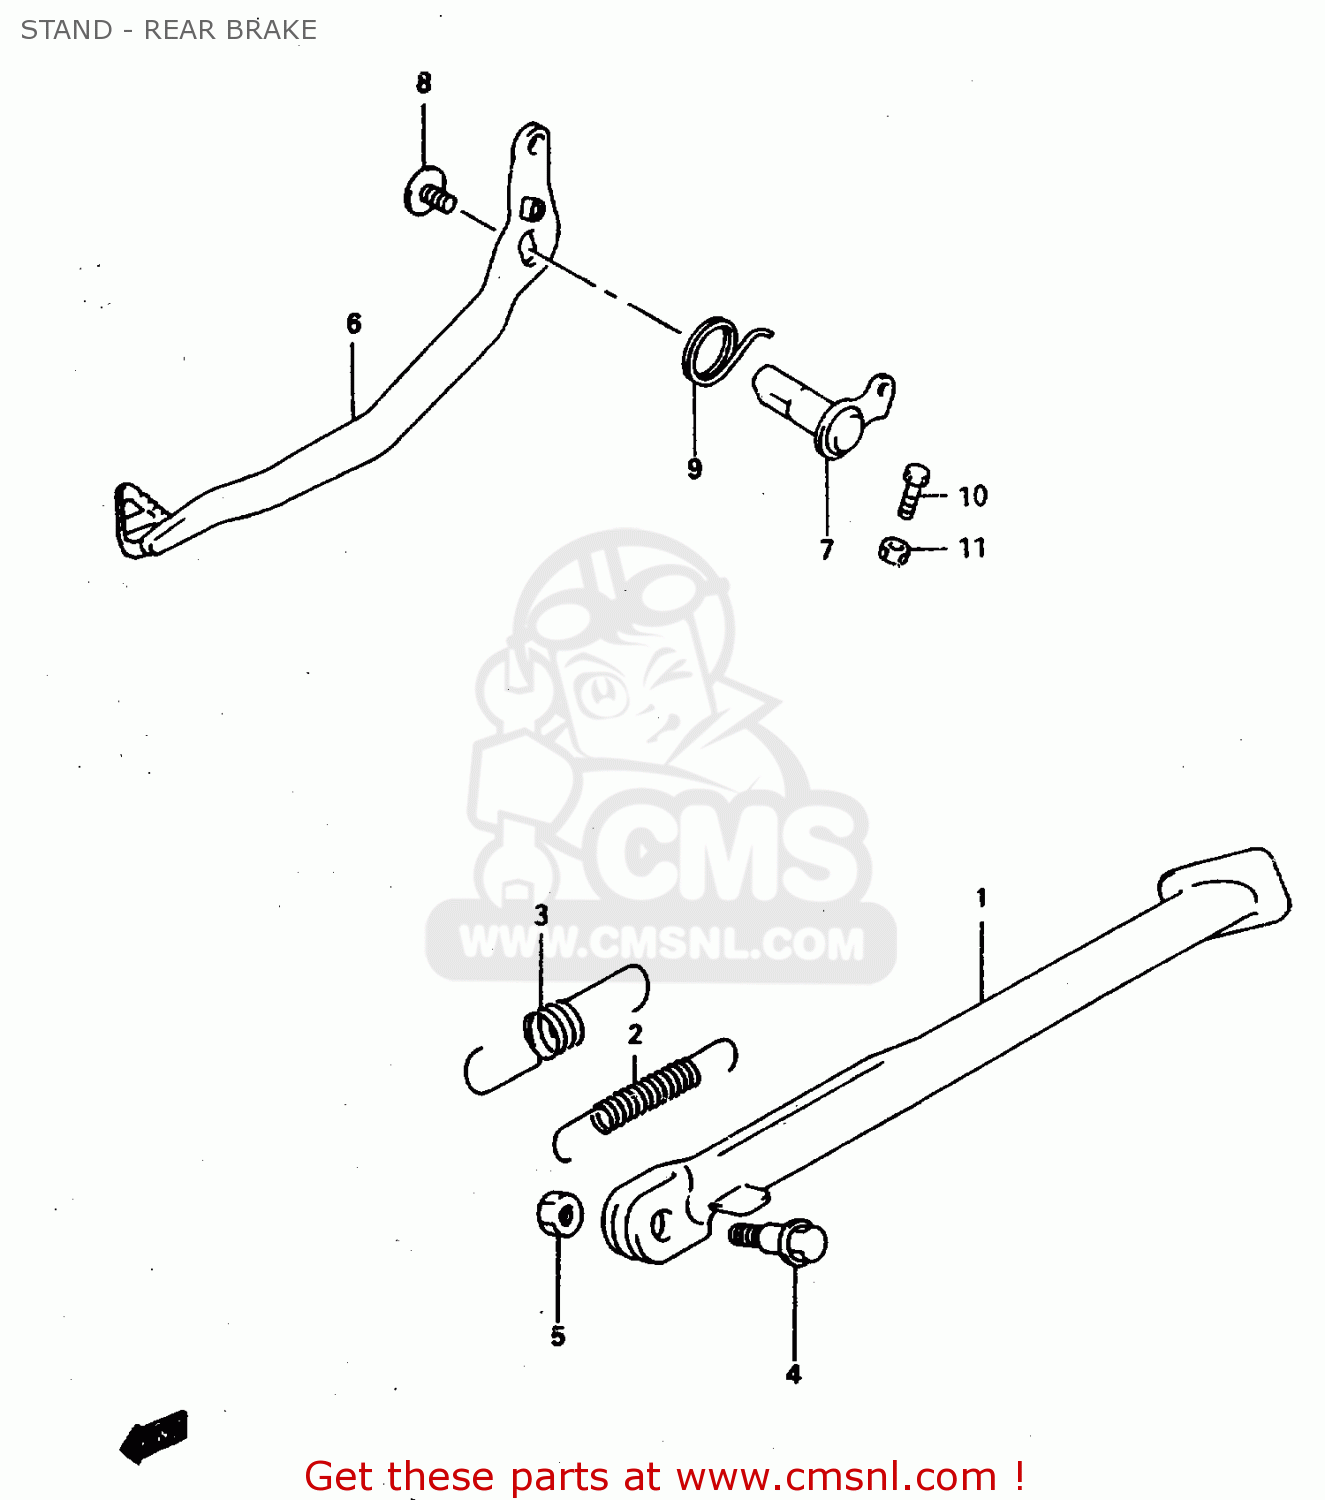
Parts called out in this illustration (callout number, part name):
1	STAND, PROP (BLACK)
2	SPRING
3	SPRING
4	BOLT(10X33.5)
5	NUT
6	PEDAL,BRAKE
7	ARM,BRAKE PEDAL ROD
8	BOLT(8X14)
9	SPRING
10	BOLT(6X23)
11	NUT 6MM
